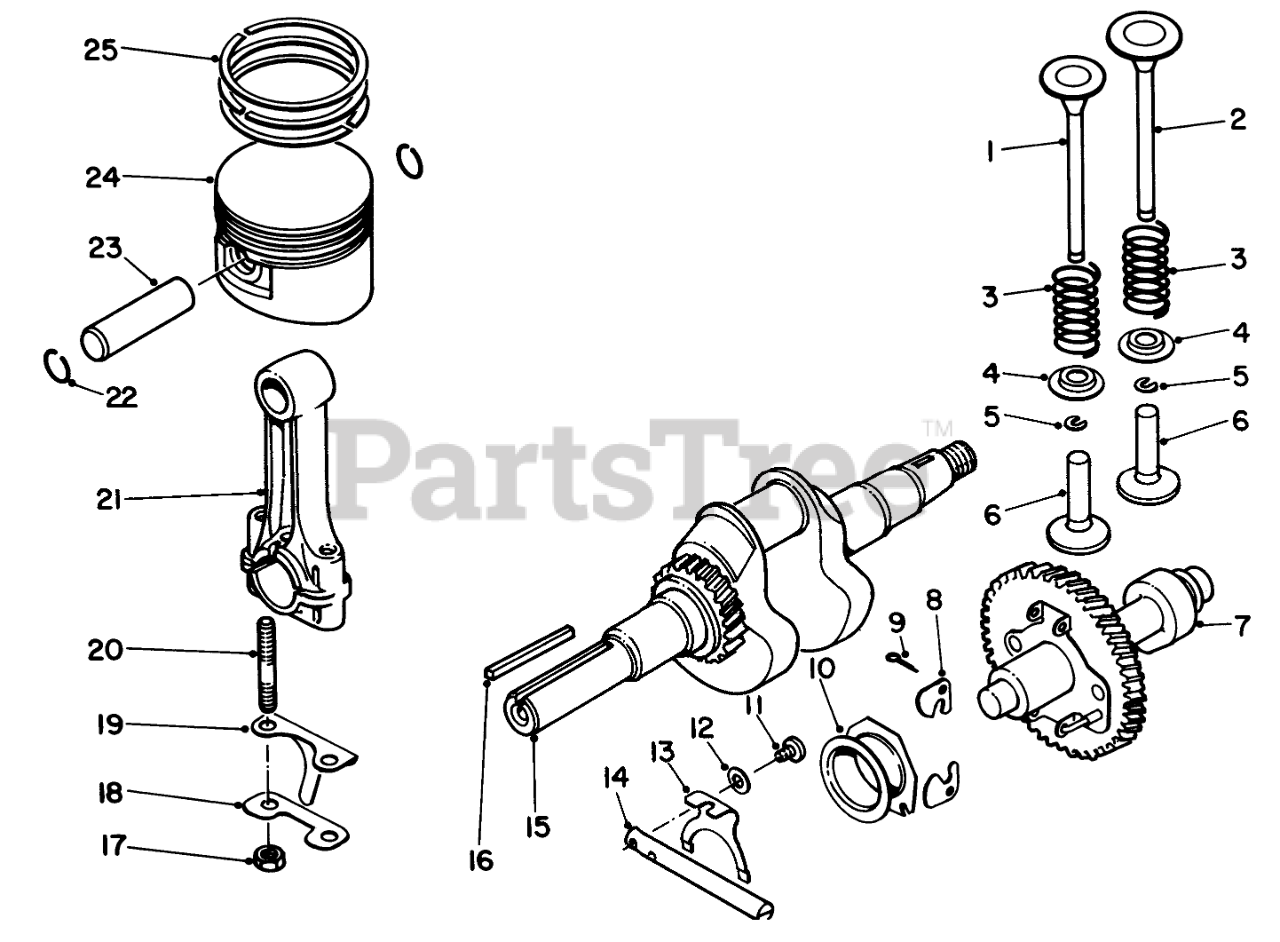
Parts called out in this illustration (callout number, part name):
1	VALVE, INTAKE
2	VALVE, EXHAUST
3	Spring-Valve
4	Retainer-Spring
5	Cotter-Valve
6	TAPPET
7	Cam Shaft
8	BRACKET
9	Washer
11	Spacer
12	SHIFT PLATE
15	Cotter Pin
16	SCREW
17	Washer
18	Crankshaft Assembly
19	SHAFT-THROTTLE TURN
22	LOCK PLATE
23	Plate-Splasher
24	Connecting Rod Assembly (Incl. Ref. #21-23)
25	CIRCLIP
26	Pin Piston
27	Piston Std.
28	Ring Set-Piston Std.
